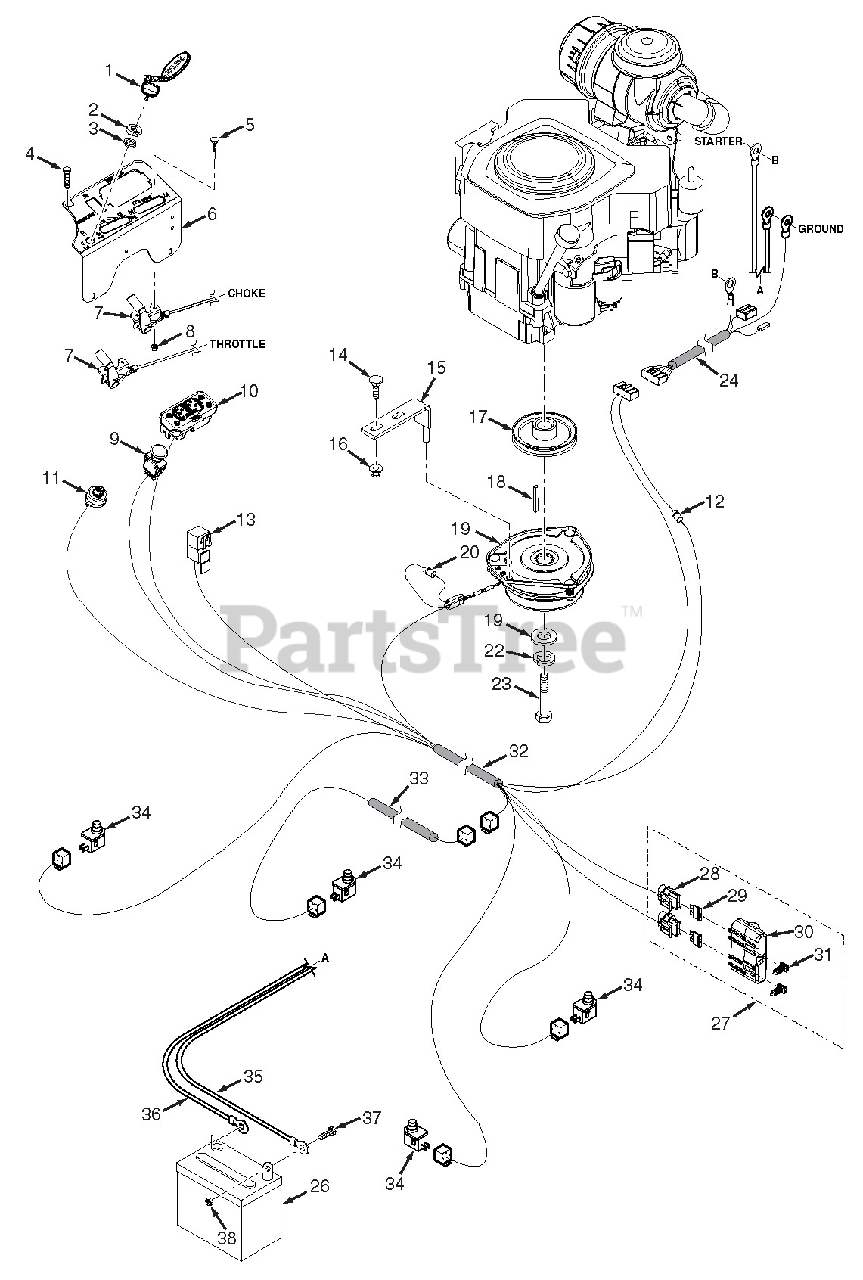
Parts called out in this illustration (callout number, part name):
1	Key, Ignition
1	Key Assembly w/Fob
2	Nut, Hex 5/8-32
3	Lockwasher, 5/8" Internal
4	Bolt, Hex Head Serrated Flange 1/4-20 x 1/2"
5	Bolt, Carriage #10-24 x 1/2"
6	Instrument Panel w/Decal
7	Control Cable
8	Locknut, #10-24
9	Switch, PTO
10	Tiger Eye Cluster Gauge
11	Switch, Starter
12	Diode
13	Relay
14	Bolt, Carriage 5/16-18 x 3/4"
15	Anti-Rotation Weldment
16	Nut, Flange Elastic Stop 5/16-18
17	Pulley, 5" Dia. - 1.125 Bore
18	Key, 1/4 x 1/4 x 3-1/2"
19	Clutch, GT3.5 - 1.125 Bore
20	Diode, 600V - 6A
21	Flatwasher, 7/16-.469 x 1.75 x .25
22	Lockwasher, 7/16" Spring
23	Bolt, Hex Head 7/16-20 x 2-1/4" w/Patch
24	Wire Harness Adapter, Kawasaki
25	Diode
26	Battery, 350 CCA
27	Double Fuse Assy.
28	Fuse Holder
29	Fuse, 20 Amp
30	Cover, Sealed Double
31	Clip, Wire
32	Wire Harness, SCZ48/52
33	Wire Harness, Operator Platform
34	Switch
35	Battery Cable, 25" Red (Kawasaki)
36	Battery Cable, 27" Black
37	Bolt, Hex Head 1/4-20 x 1/2"
38	Nut, 1/4-20 UNC
